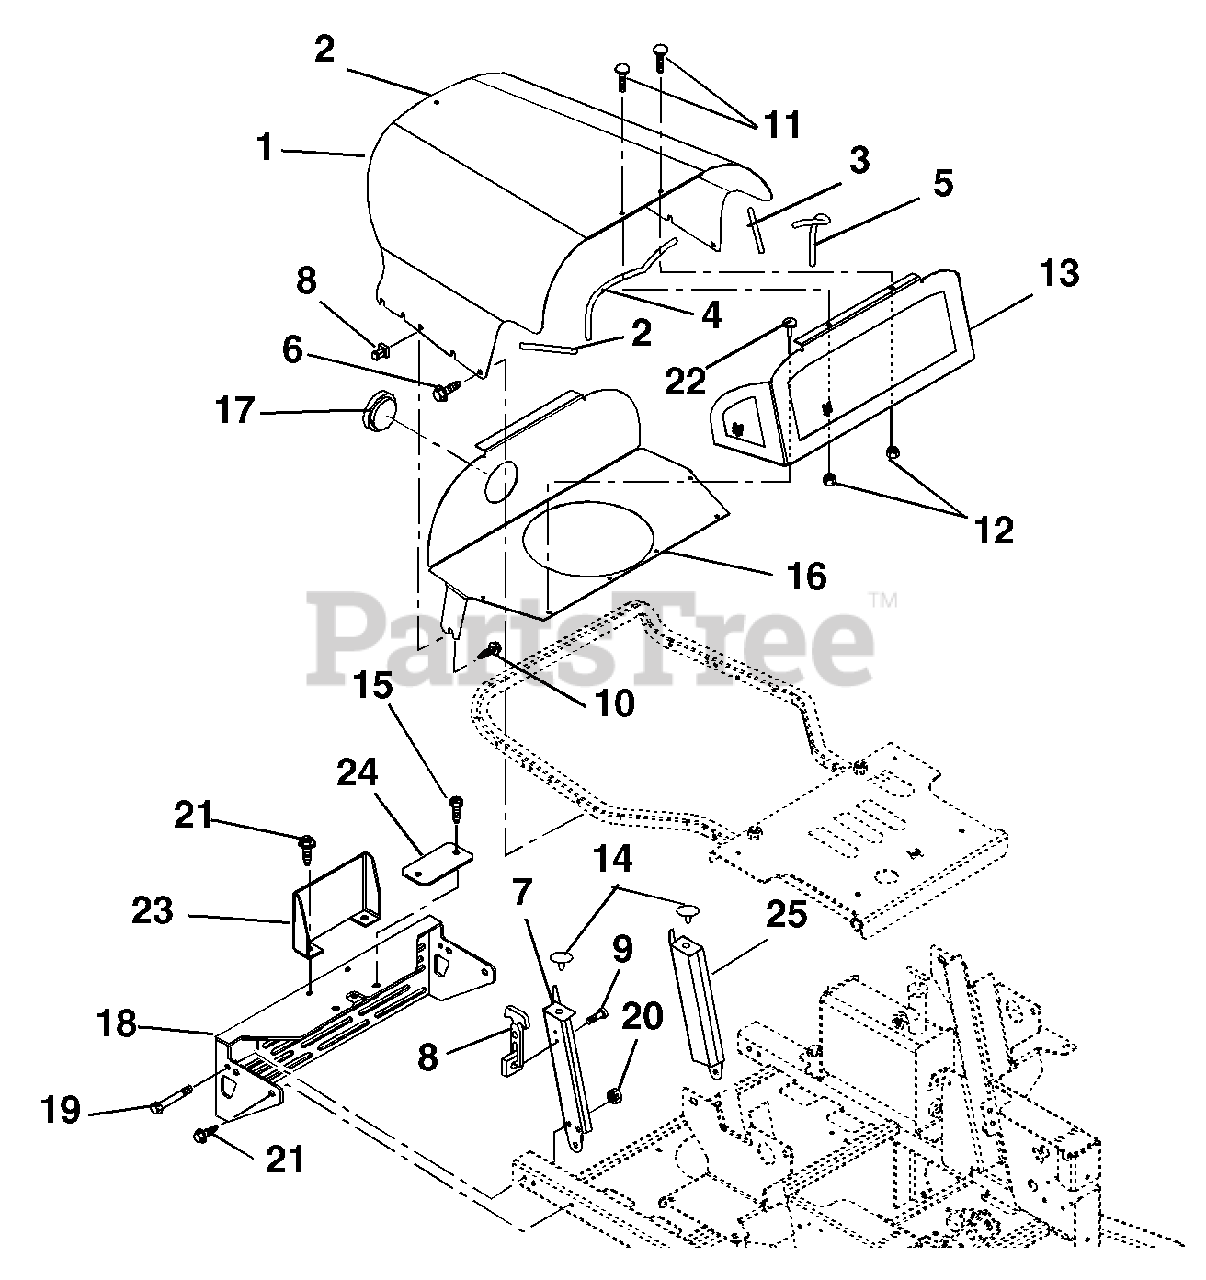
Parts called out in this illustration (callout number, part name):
2	Seal-Trim-Lok Bulk .06 Bubble
3	Seal-Trim-Lok Bulk .06 Bubble
4	Seal-Trim-Lok Bulk .06 Bubble
5	Seal-Trim-Lok Bulk .06 Bubble
6	Screw-Tapping .38-16 x .50 Hex Washer Head
7	Hood Support Right-Hand
8	Latch-Rubber
9	Screw-Machine 10-24 x .50 Hex Washer Head
10	Screw Machine 10-24 x .50 Hex Washer Head
11	Bolt-Round Head Square Shank .25-20 x .50 Grade 5
12	Nut-Locking-Nylon .25-20
13	Weldment, Plenum
14	Button Bumper
15	Screw-Tapping .250-20 x .37 Hex Washer Head (020)
16	Back, Plenum
17	Plug, Hole-3.38 (032, 033)
18	Bumper-Rear
19	Bolt-Hex .38-16 x 2.75 Grade 5
20	Nut-Locking-Center .38-16
21	Screw-Tapping .38-16 x .75 Hex Washer Head (020)
21	Screw-Tapping .38-16 x .75 Hex Washer Head (029, 030, 032, 033, 034, 035)
22	Rivet-Pop .18 x .402
23	Guard, Muffler (029, 030, 032, 033, 034, 035)
24	Plate, Bumper (020)
25	Weldment, Hood Support-Left Hand
